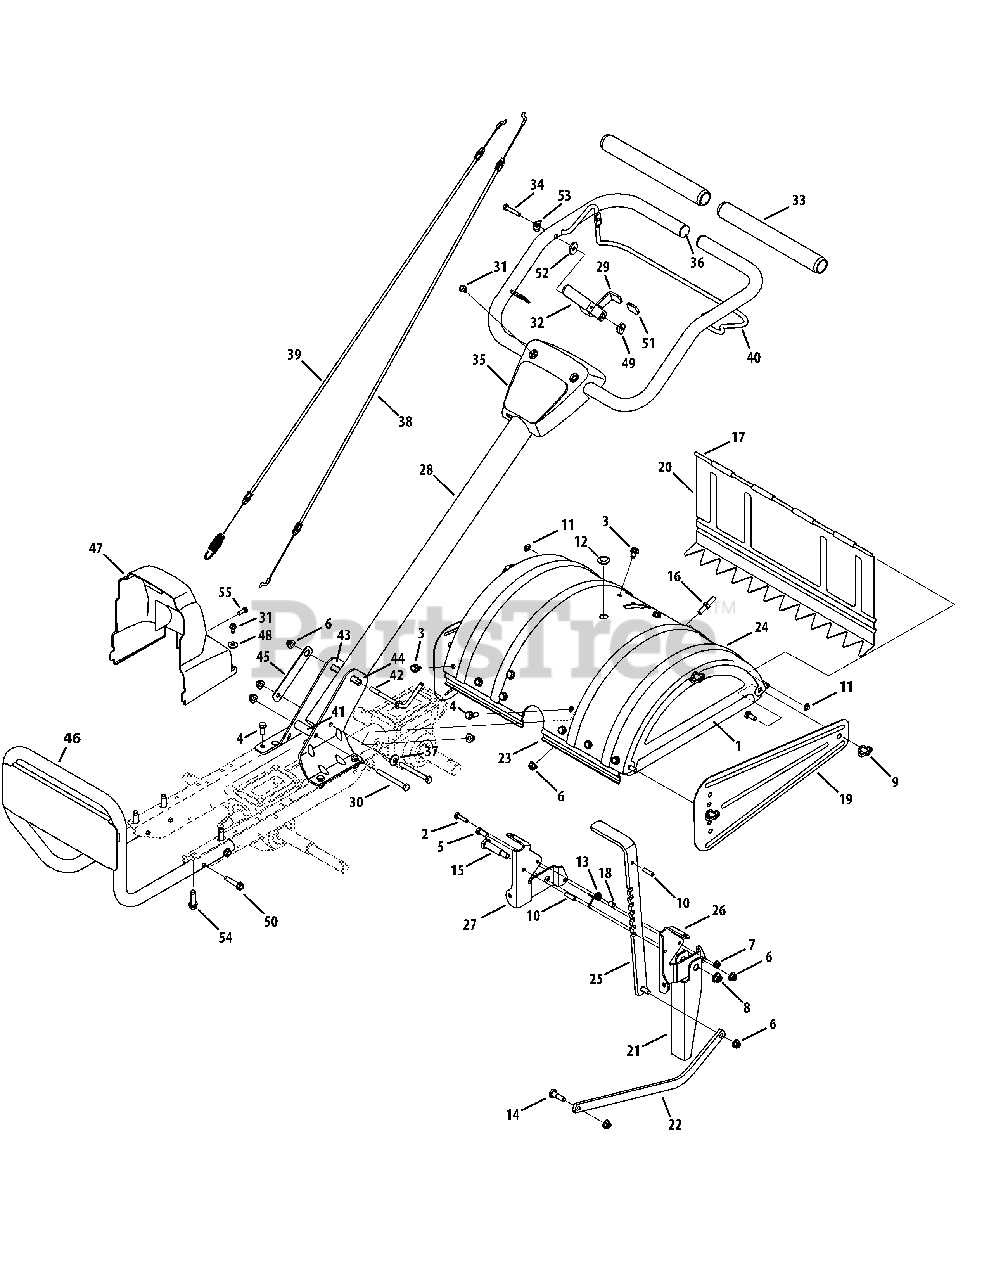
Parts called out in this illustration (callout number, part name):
1	End Cover Assembly
2	Hex Head Screw, 1/4-20 x 1
3	Hex Head Screw, 5/16-18 x .625
4	Hex Head Screw, 5/16-18 x .875
5	Hex Head Screw, 5/16-18 x .75
6	Nylon Hex Lock Nut, 5/16-18
7	Nylon Hex Lock Nut, 1/4-20
8	Flange Lock Nut, 3/8-16
9	Wing Nut, 5/16-18
10	Spirol Pin
11	Cap Nut, 1/4 Rod
13	Torsion Spring
14	Shoulder Screw, .405 x .435 5/16-18
15	Shoulder Screw, .498 x 1.635
16	Stop Screw
17	Tiller Flap Rod
20	Rear Tine Shield
21	Reverse Stop Arm
23	Tine Shield Mounting Bracket
25	Adjustable Depth Bar
26	Tail Bracket, LH
27	Tail Bracket, RH
28	Upper Handle Assembly
29	Reverse Handle Assembly
30	Hex Head Screw, 5/16-18 x 3.00
31	Self-Tapping Screw, 1/4-20 x 1/2
32	Handle Select
33	Foam Handle Grip
34	Hex Head Screw, 1/4-20 x 1.62
35	Handle Cover
36	Plug End
37	Bell Washer, .340 x .872 x .060
38	Reverse Cable
39	Forward Cable
41	Spacer, .322 x .625 x 2.00
42	Handle Crank
43	Handle Bracket, RH
44	Handle Bracket, LH
45	Retainer Nut Bracket
47	Belt Cover
48	Flat Washer, .28 x .74 x .063
49	Spacer, .375 x .165
50	Hex Head Screw, 5/16-18 x 1.50
51	Reverse Handle Grip
52	Flat Washer, .265 x .938 x .120
53	Saddle Washer, .320 x .930 x .060
54	SEMS Screw, 3/8-16
55	Self Tapping Screw, 1/4-14 x .625
